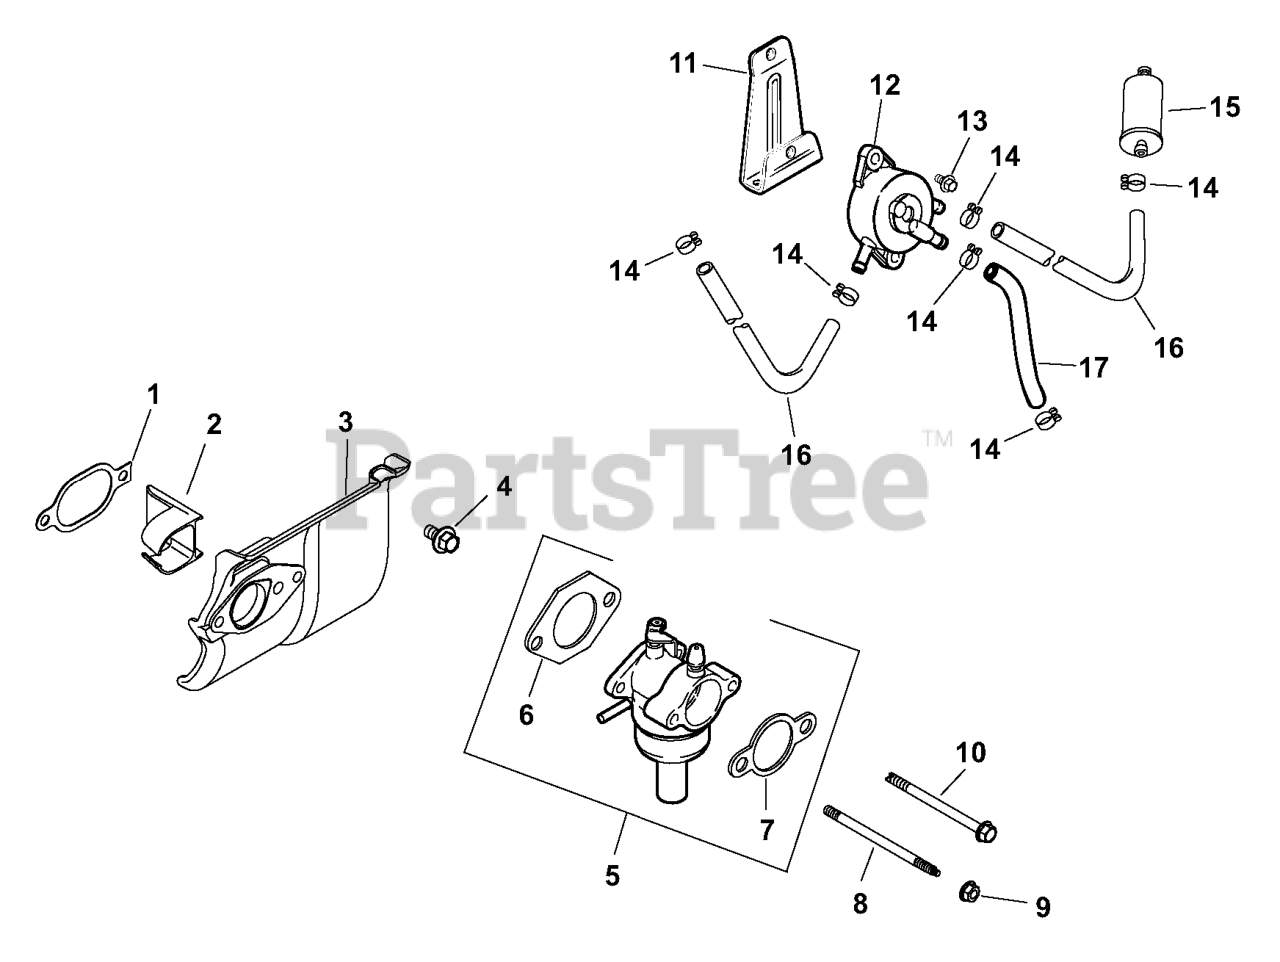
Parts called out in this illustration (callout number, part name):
1	Gasket, Heat Deflector
2	Insert, Intake Port
3	Deflector, Heat
4	Screw, Flg M6x1.0x20
5	Kit, Carburetor W/gaskets
6	Gasket, Air Cleaner Base
7	Gasket, Carburetor
8	Stud, M6x1.0x100
9	Nut, Flg M6x1.0
10	Screw, Flg Thd Frm M5x0.8x10
11	Bracket, Fuel Pump Mounting
12	Pump, Fuel
13	Screw, Flg Thd Frm M6x1.0x16
14	Clamp, Hose
15	Filter, Fuel
16	Line, Fuel (24"-cut To Length)
17	Line, Fuel 10"
